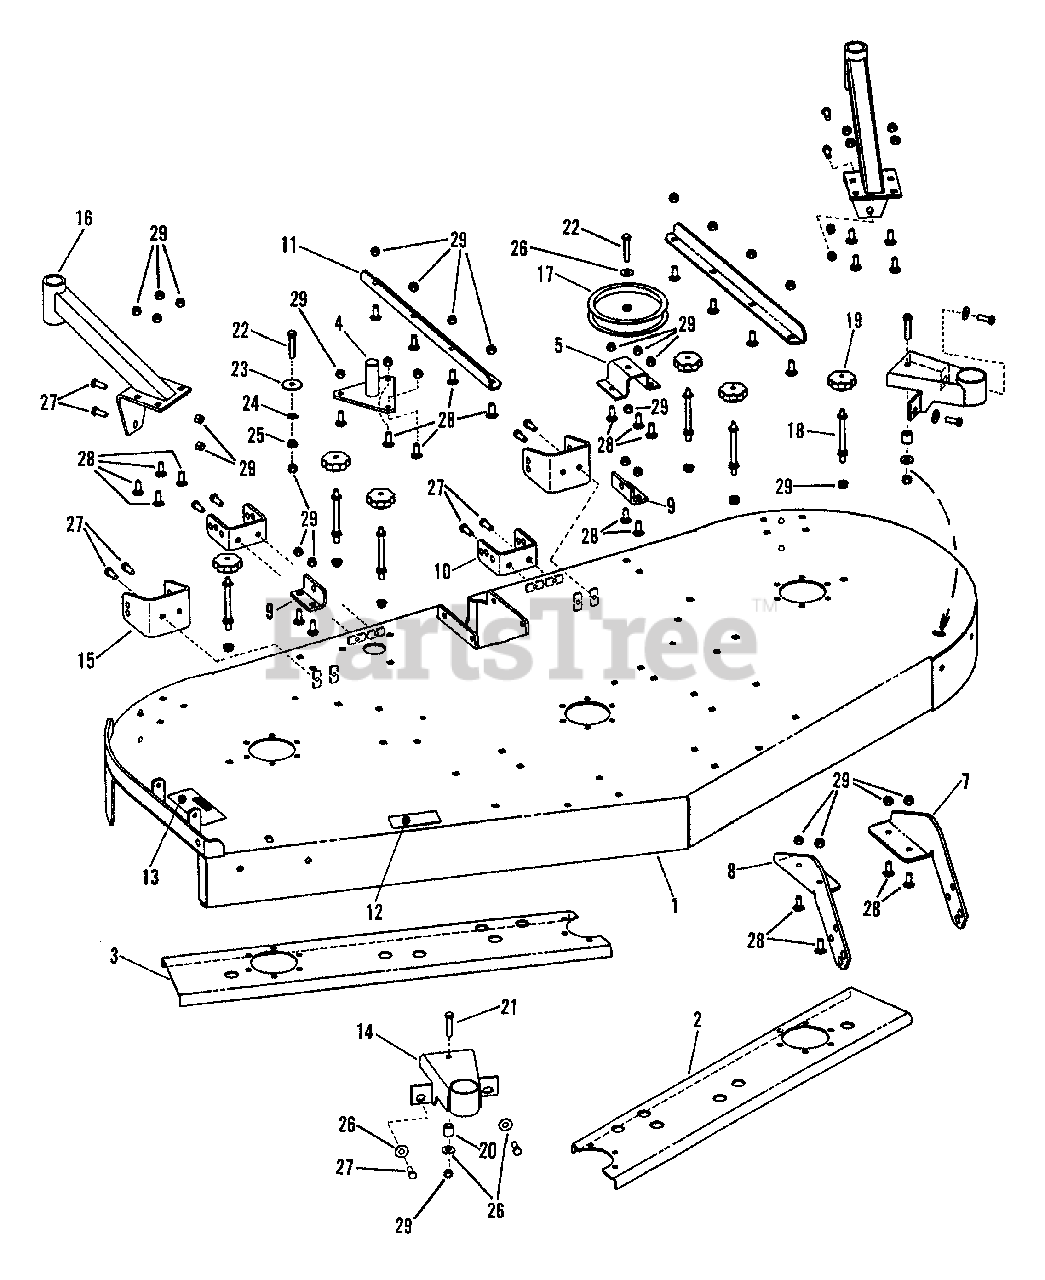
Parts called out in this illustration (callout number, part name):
1	WELDMENT, 73" Deck
2	CHANNEL, L.H. Deck Stiffener
3	CHANNEL, R.H. Deck Stiffener
4	WELDMENT, Idler Pivot
5	STAND, Fixed Idler
7	ROLLER MOUNT, Left Hand
8	ROLLER MOUNT, Right Hand
9	HANGER BRACKET, Rear Deck Lift
10	BRACKET, Rear Deck Hanger
11	STIFFENER, Deck
12	DECAL, 73" Deck
13	DECAL, Danger
14	WELDMENT, Gage Wheel
15	BRACKET, Gage Wheel
16	WELDMENT, Caster Support
17	PULLEY, Idler 5-1/2" O.D.
18	STANDOFF, 3-1/2" (5/16-18 Top; 3/8-16 Bottom)
19	KNOB, 5/16-18
20	SPACER
21	SCREW, 3/8-16 x 1-3/4" Hex Head Cap, Grade 5
22	BOLT, 3/8-16 X 2, GD5, CZ
23	WASHER, .406 I.D. x 1-1/2" O.D. Flat
24	RETAINER, 3/8" Bolt
25	NUT, 3/8-16 HEX SERRATED FLANGE
26	WASHER, 3/8" USS
27	BOLT, 3/8-16 X 1" GD5 CZ
28	BOLT, 3/8-16 x 1" square Neck Carriage, Grade 5
29	NUT, 3/8-16 HEX NYLON LOCK
